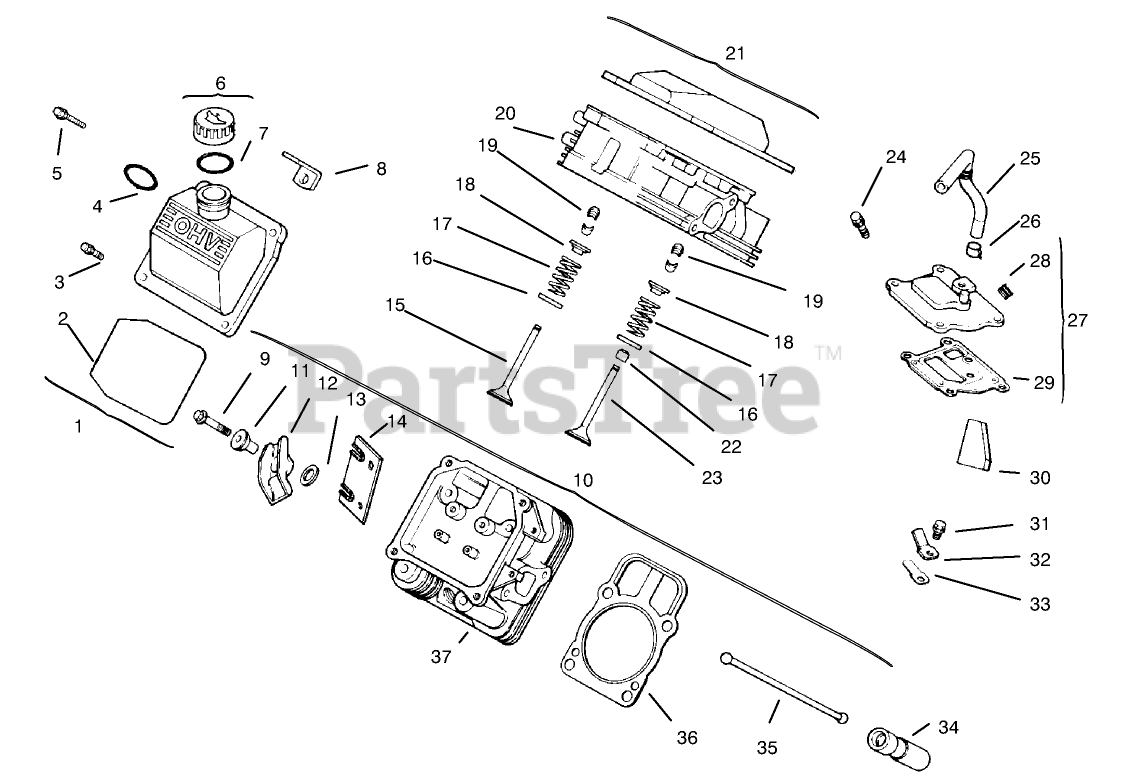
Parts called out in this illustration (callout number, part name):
1	Kit-Valve Cover (Incl. Ref. #2-4)
3	Screw-Shoulder (M6x1.0x30)
4	O-Ring
5	SCREW-FLANGE (M10X1.5X90)
6	Kit-Oil Fill Cap (Incl. Ref. #7)
7	O-Ring
8	STRAP-LIFTING
10	Kit-Valve Train (Incl. Ref. #11-14 & 35)
11	Pivot-Rocker Arm
12	Arm-Rocker
13	Washer-Flat
14	Plate-Guide
15	VALVE-EXHAUST (STD)
16	RETAINER-SPRING
17	SPRING-VALVE
18	CAP-SPRING, VALVE
19	RETAINER KIT
20	#1 Cylinder Head ASM
21	Kit-Valve Cover (Incl. Ref. #2 & 3)
22	Seal-Stem, Valve
23	VALVE-INTAKE (STD)
25	Hose-Breather
26	Clamp
27	Kit-Breather w/Plug (Incl. Ref. #28 & 29)
28	Plug
29	Gasket-Breather
30	Filter-Breather
32	Retainer-Reed, Breather
33	REED-BREATHER
34	Lifter-Valve
35	Rod-Push
36	Gasket-Head, Cylinder
37	#2 Cylinder Head ASM
